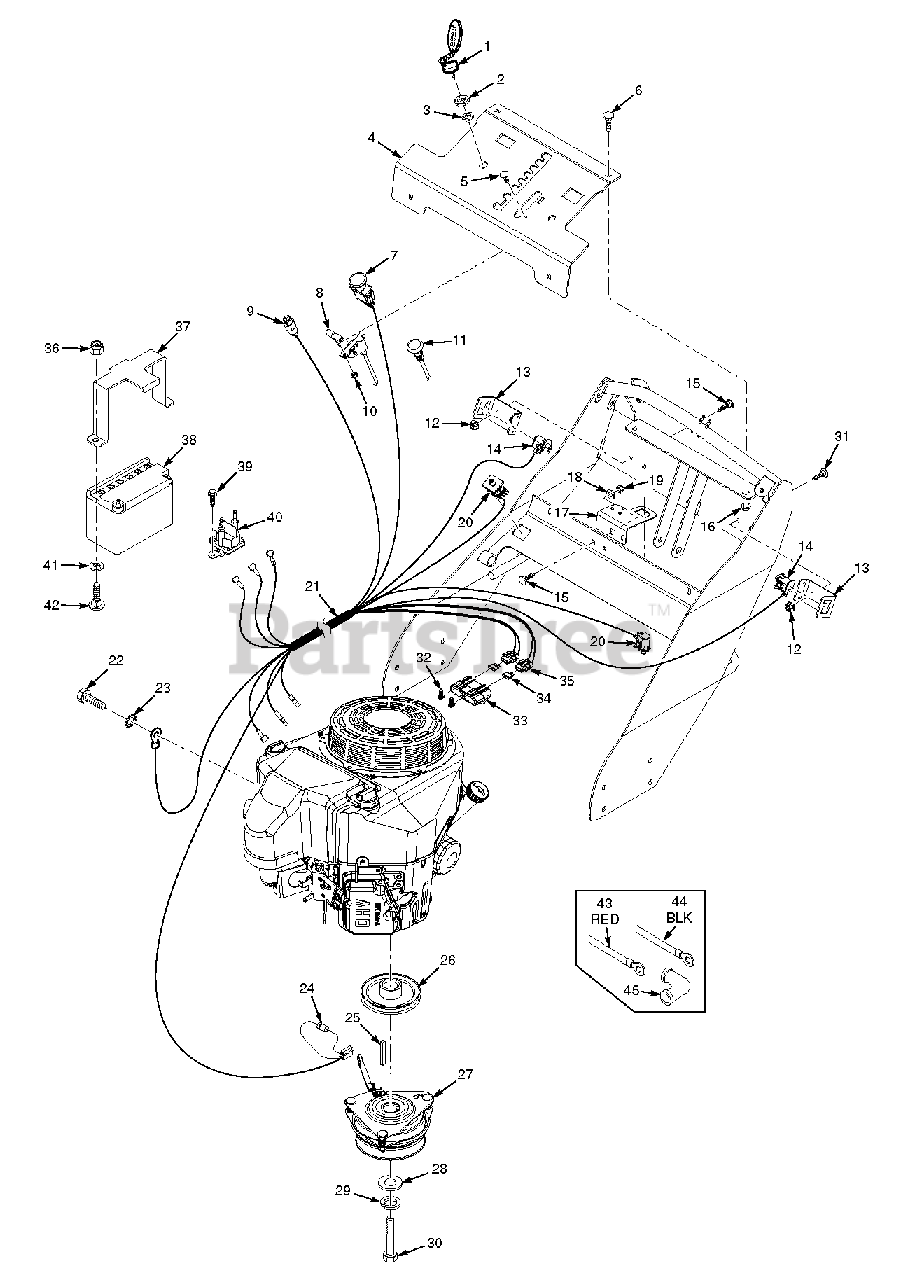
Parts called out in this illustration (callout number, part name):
1	Key Assembly w/Fob
1	Key w/Shroud
2	Nut, 5/8-32 Special
3	Lockwasher, 5/8" Internal Tooth
4	Instrument Panel w/Decal
5	Bolt, Carriage #10-24 x 1/2"
6	Bolt, Carriage 5/16-18 x 3/4"
7	PTO Switch
8	Throttle Cable
9	Key Switch
10	Nut, Elastic Stop #10-24
11	Choke Control
12	Nut, Serrated Flange 1/4-20
13	Bracket, Operator Presence Switch
14	Switch
15	Bolt, Carriage 1/4-20 x 3/4"
16	Nut, Serrated Flange 5/16-18
17	Bracket, Neutral Switch
18	Flatwasher, 5/16-.375 x .875 x .083
19	Nut, Elastic Stop 1/4-20
20	Switch, Brake Interlock
21	Wire Harness
22	Bolt, Hex Head M8-1.25 x 14
23	Lockwasher, 5/16" External Tooth
24	Diode
25	Key, 1/4 x 1/4 x 2-1/2"
26	Pulley, 4-1/2" Dia. 1" Bore
27	Electric Clutch Assembly
28	Flatwasher, 7/16-.469 x 1.75 x .25
29	Lockwasher, 7/16" spring
30	Bolt, Hex Head 7/16-20 x 3" w/t Patch
31	Bolt, Carriage 1/4-20 x 1-1/4"
32	Clip, Wire
33	Cover, Sealed Double
34	Fuse, 20 Amp
35	Fuse Holder
36	Nut, Elastic Stop 5/16-18
37	Bracket, Battery
38	Battery (not available through Scag)
39	Screw, Self Tapping 1/4-20 x 3/4"
40	Solenoid, Sealed
41	Nut, Push-On 5/16"
42	Bolt, Carriage 5/16-18 x 1"
43	Cable, Battery - Red
44	Cable, Battery - Black
45	Rubber Boot
